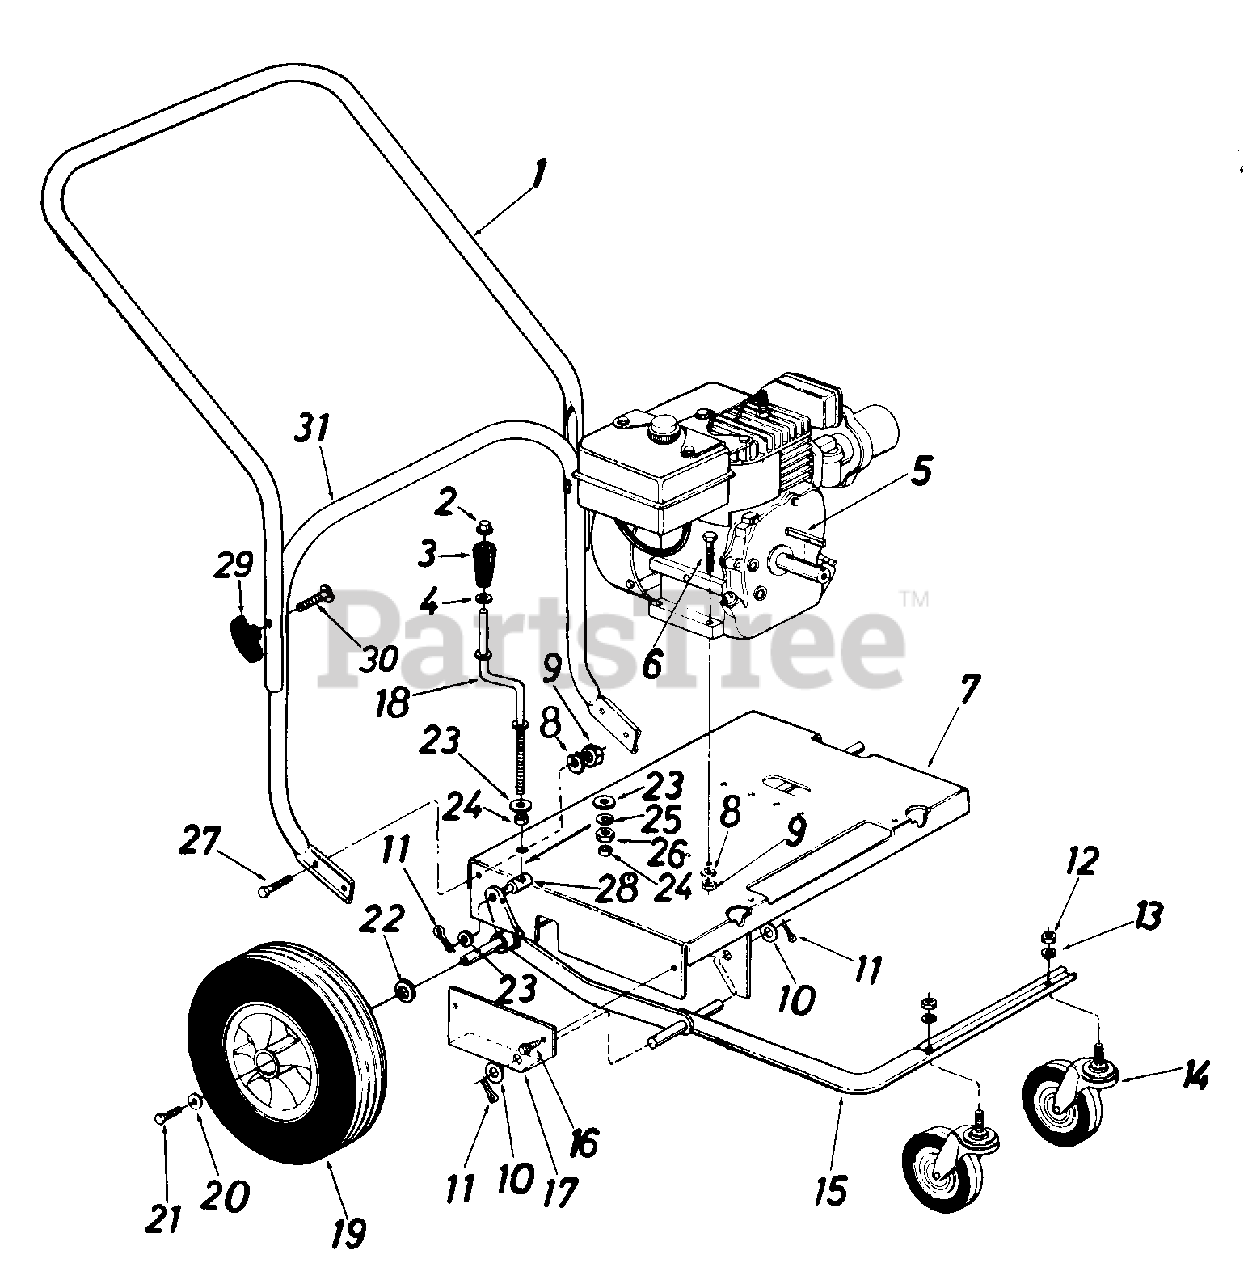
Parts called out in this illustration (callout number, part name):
2	Push Nut 3/8" Rod
3	Crank Knob
4	F l .-Wash . .385 " I . D. x .62" O.D.
5	Sq. Key 1/4" x 2.0" Lg.
6	Hex Bolt 5/16-18 x 1.50" Lg.*
9	Hex Nut 5/16-18 Thd.*
10	Fl.-Wash. .63" I.D. x 1.25"O.D.
11	Cotter Pin 1/8" Dia. x 1.0" Lg.
12	Hex Nut 1/2-13 Thd.*
13	L.-Wash. 1/2" I.D.*
14	Swivel CasterWheel 5" Dia. x 1.25"
19	Wheel Ass y. Comp. 12" x 3" (Plastic)
20	Fl.-Wash. 34" I.D. x .87"O.D.
21	Hex Locking Bolt 5/16-24 x.62" Lg.
22	Fl.-Wash.
23	Fl.-Wash. .38" I.D. x .57" O.D.
24	Spacer .382" I.D. x .50" O.D. x .180" Lg.
25	L.-Wash. 3/8" I.D.*
26	Hex Nut 3/8-8 Thd.
27	Hex Bolt 5/1 6-1 8 x .75" Lg.*
28	Ferrule
29	Hand Knob
30	Carriage Bolt 5/16-18 x 2.0" Lg.
